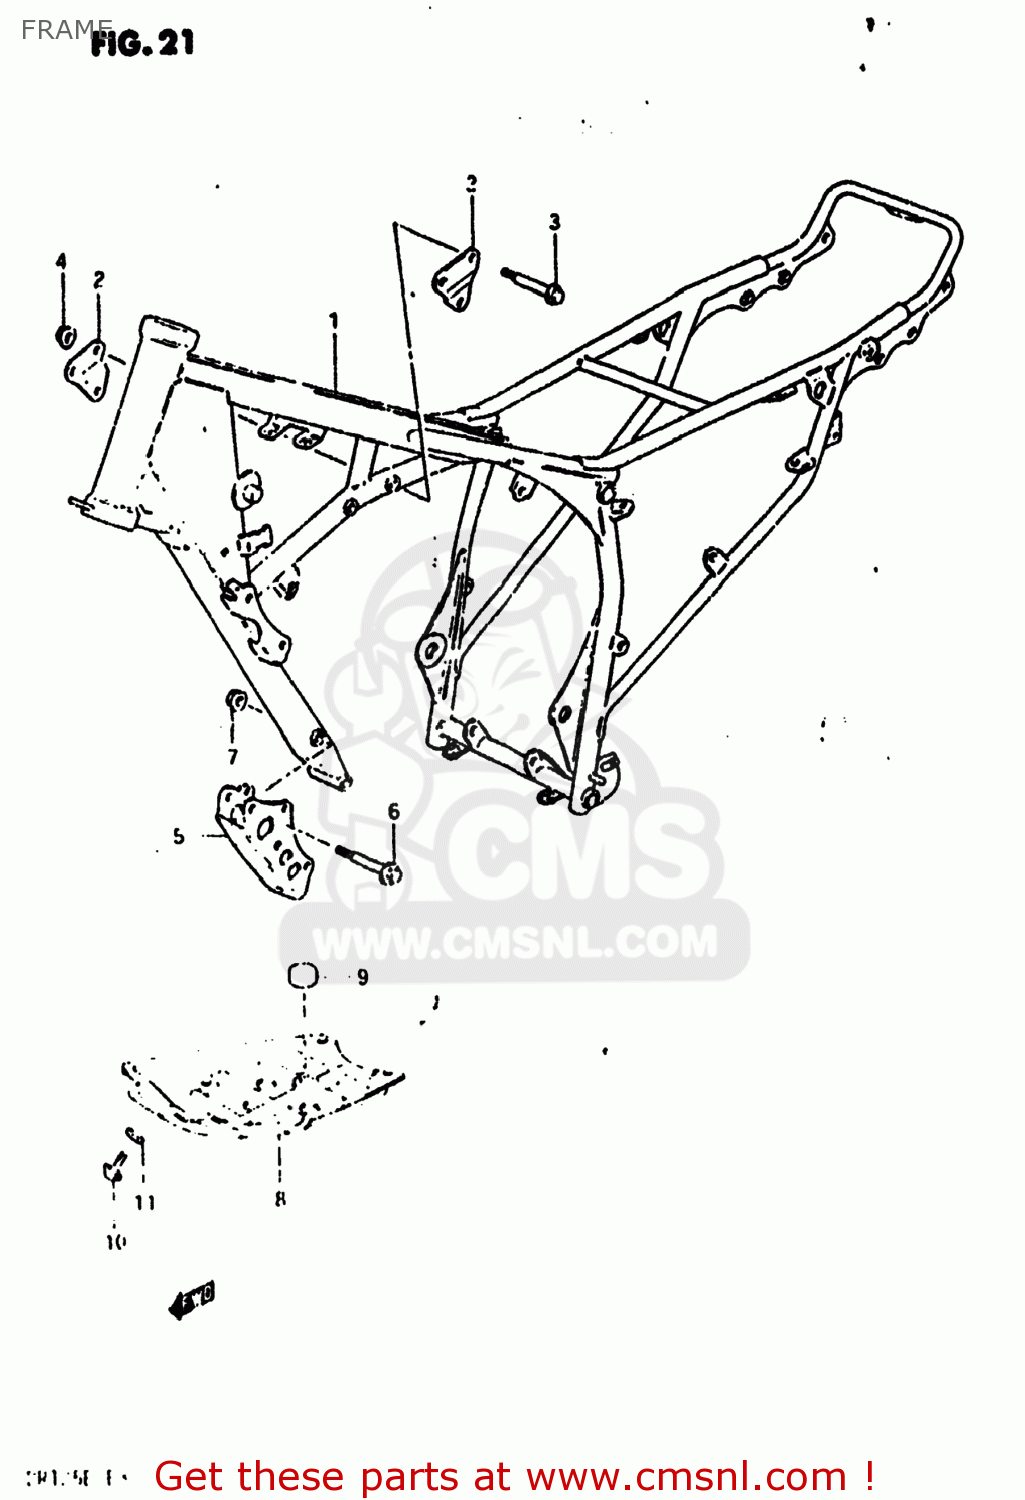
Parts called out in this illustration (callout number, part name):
1	FRAME
2	PLATE,ENGINE MOUNTING
3	BOLT
4	NUT
5	PLATE,ENGINE MOUNTING
6	BOLT 8X65
7	NUT
8	PROTECTOR,ENGINE
9	CUSHION
10	BOLT
11	WASHER
